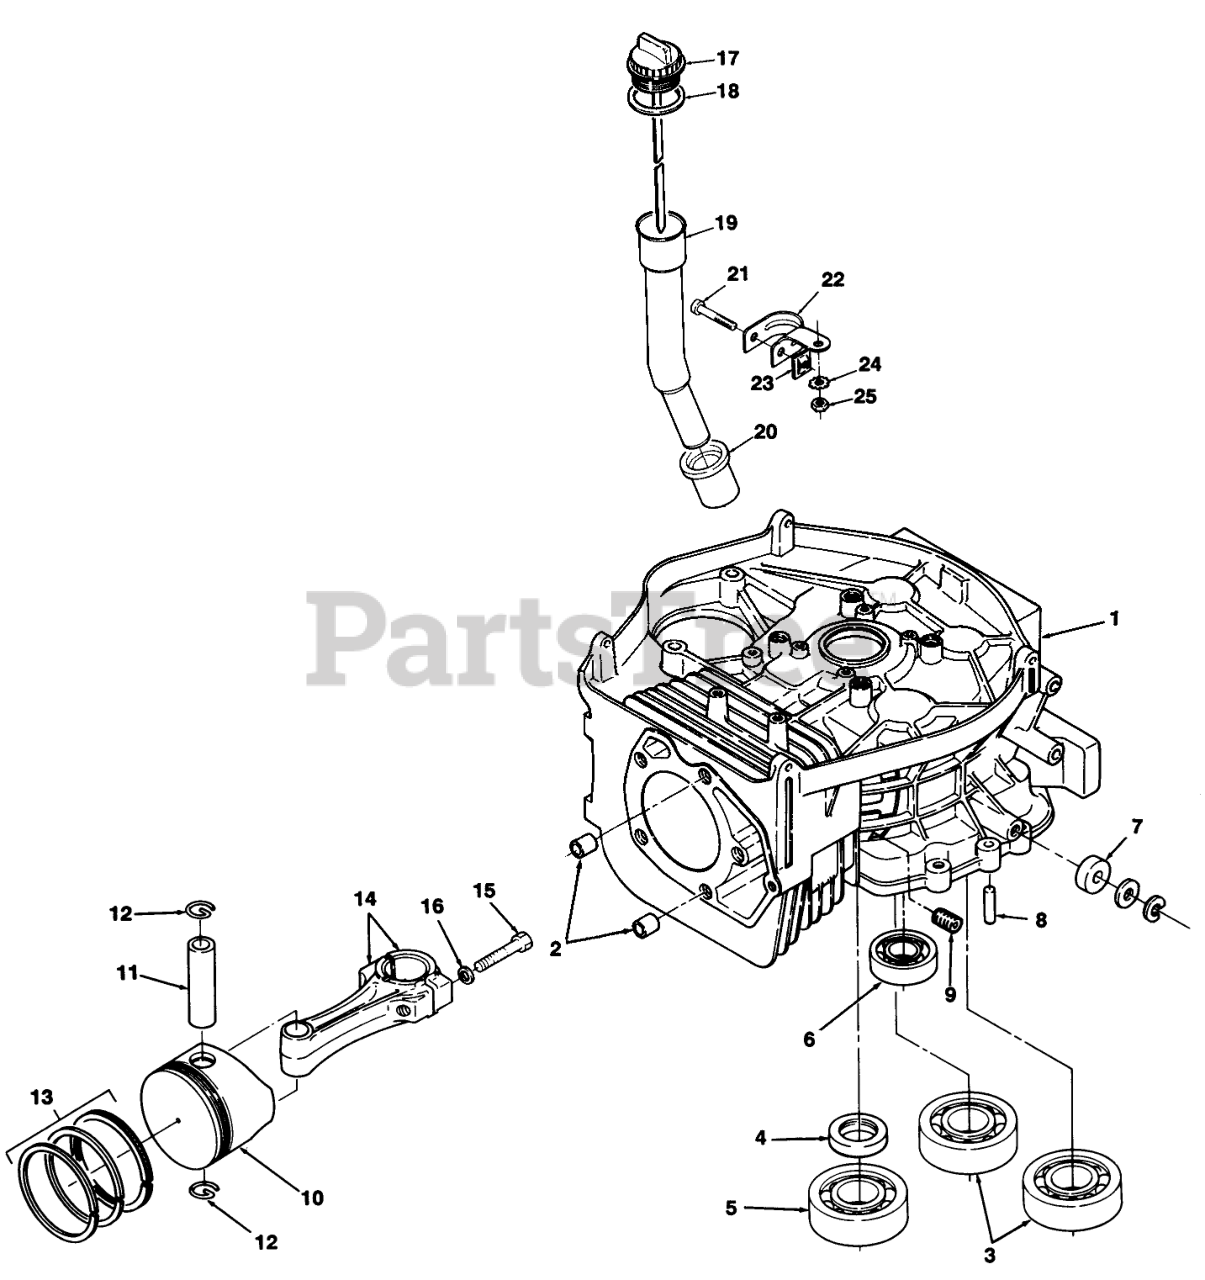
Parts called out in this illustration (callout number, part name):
1	Block-Short
2	PIN-DOWEL HOLLOW
3	BRNG-BALL BAL SHFT L
4	SEAL-OIL CRNKSHFT UP
5	BEARING-BALL CRANKSH
6	BEARING-BALL CAMSHFT
7	SEAL-GVR SHAFT LEVER
8	PIN-ALIGNMENT
9	Plug-Pipe
10	Kit-Piston (Standard)(Incl. Ref. #11 & 12)
11	PIN-PISTON
12	RING-RETAINING
13	Piston Ring Set-Standard
14	Kit-Connecting Rod (Standard)(Incl. Ref. #15 & 16)
15	Bolt
16	WASHER-CONN ROD
17	Indicator (Incl. Ref. #18)
18	O-Ring
20	Seal
21	SCREW - PAN HEAD
22	BRACKET
23	NUT - SPEED
24	WASHER
25	Nut
